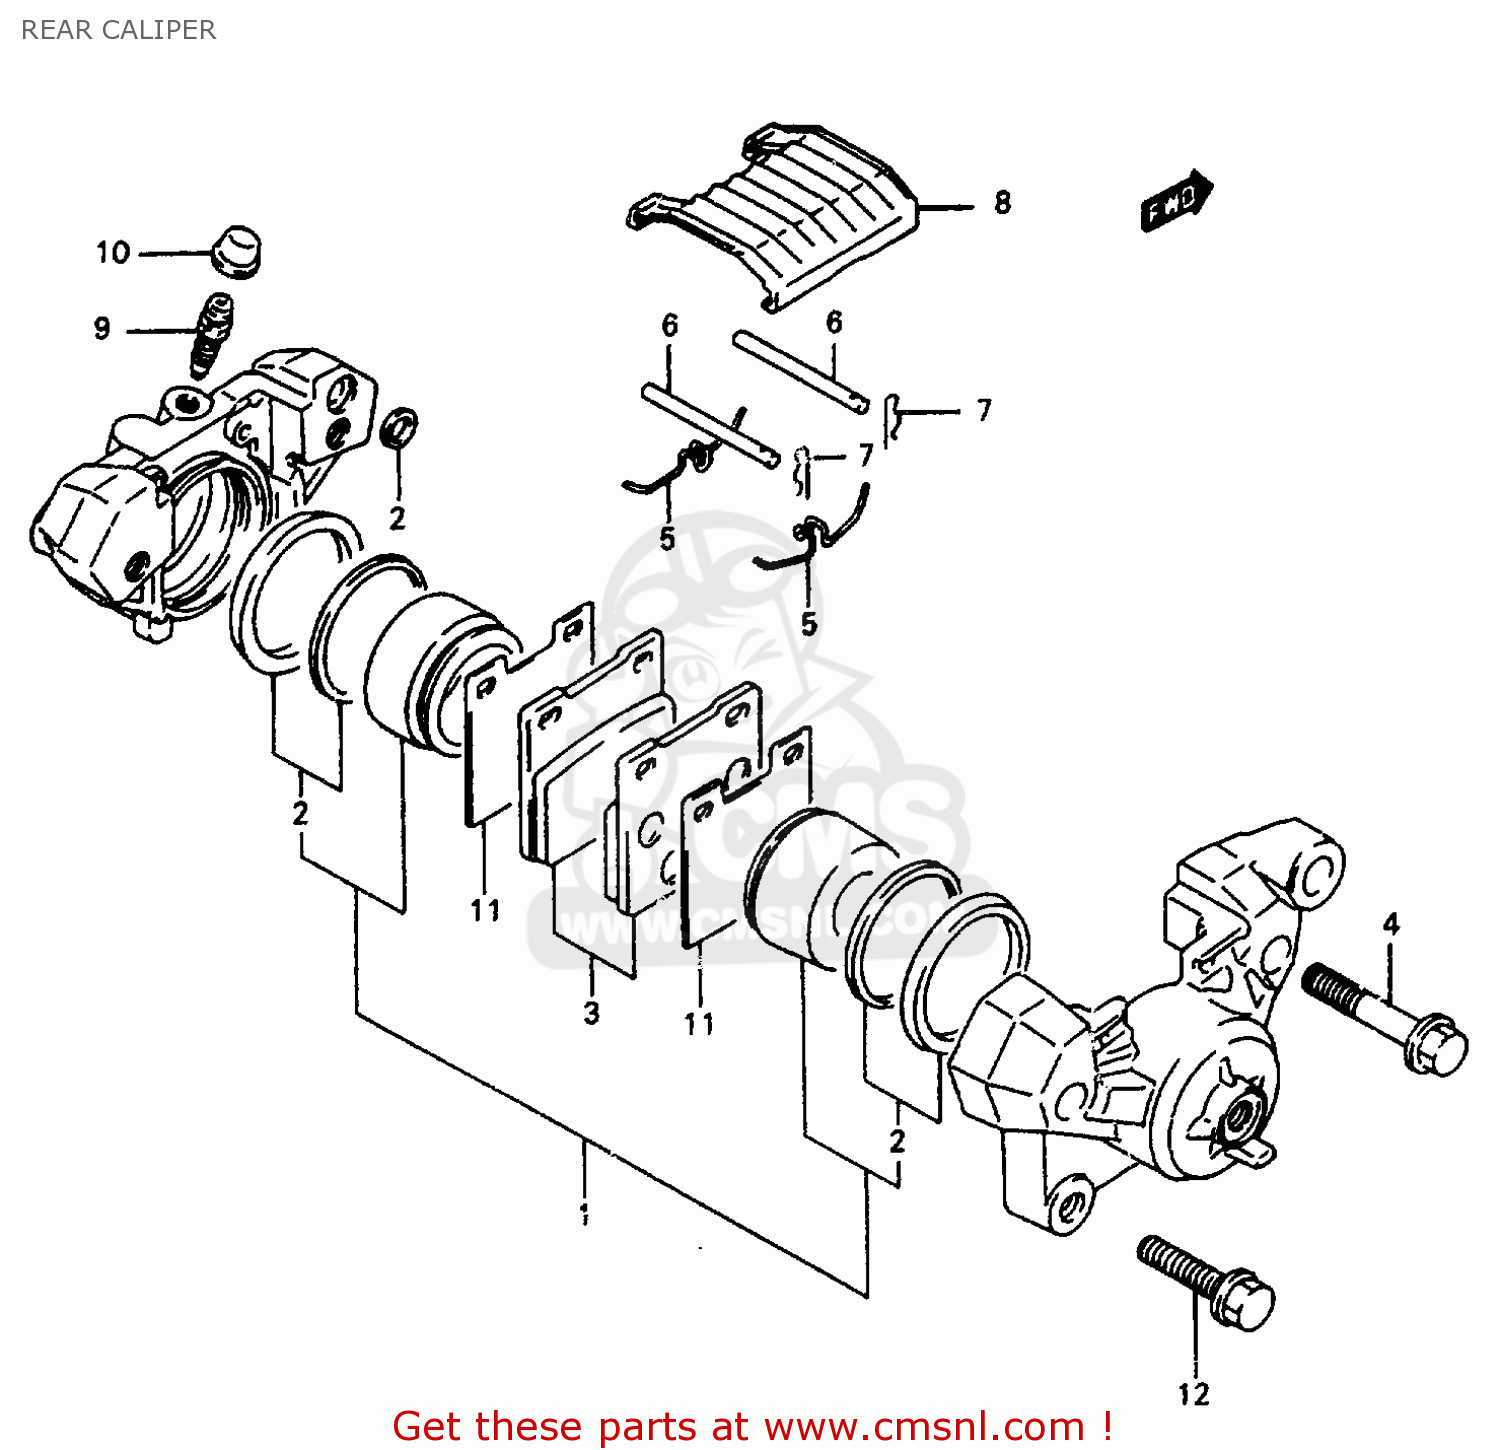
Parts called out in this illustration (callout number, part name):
1	PISTON SET
2	SEAL SET,PISTON
3	PAD SET (NAS)
4	BOLT,HOUSING
5	SPRING
6	PIN,PAD
7	CLIP,PAD PIN
8	COVER
9	BLEEDER
10	CAP,BLEEDER PLUG
11	SHIM,PAD
12	BOLT
